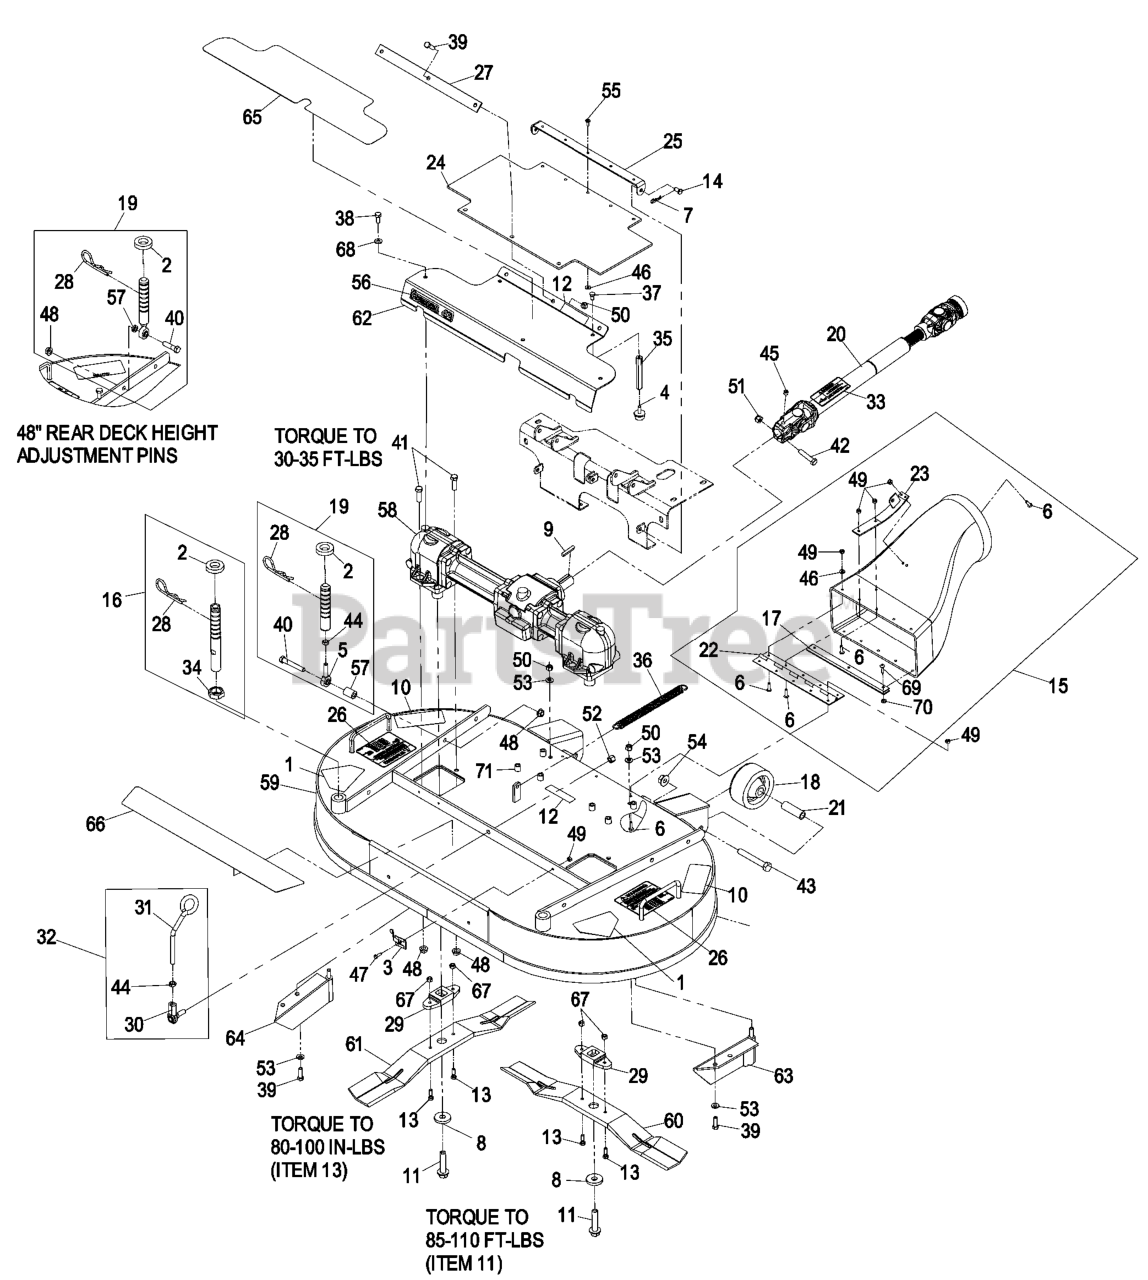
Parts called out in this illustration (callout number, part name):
1	DECAL-DANGER
2	SPACER-DECK SUPPORT
3	CLIP-DECK, HOLD UP ROD
4	BUMPER-RUBBER
5	BALLJOINT
6	SCREW-HEAD, TRUSS
7	PIN-COTTER
9	KEY-SQUARE
10	DECAL-TORQUE
11	BOLT-BLADE
12	DECAL-COVER, MISSING
13	BOLT-SHEAR
14	PIN-CLEVIS
15	DISCHARGE TUBE ASM
16	FRONT DECK HEIGHT ADJUST
17	GUARD-PLENUM
18	ROLLER-DECK
19	REAR DECK HEIGHT ADJUST A
20	DRIVE SHAFT ASM
21	SPACER-ROLLER
22	HINGE-PIANO
23	MOUNT-SPRING
24	GUARD-PTO
25	BRACKET-GUARD, PTO
27	STRAP-DRIVE, LINE COVER
28	PIN-CUT HEIGHT
29	DRIVER-BLADE
30	BALLJOINT-RH
31	LATCH-DECK
32	DECK LATCH ASM
33	DECAL-DRIVELINE
34	NUT-JAM
35	STAND-OFF
36	SPRING-EXTENSION
37	SCREW-HH
38	SCREW-HH
39	SCREW-HH
40	SCREW-HH
41	SCREW-HH
42	SCREW-HH
43	SCREW-HH
44	NUT-HEX
45	SCREW-SET, HSH
46	WASHER-FLAT
48	NUT-HHF, WHIZ
49	NUT-LOCK, NI
50	NUT-LOCK, NI
51	NUT-LOCK, NI
52	NUT-LOCK
53	WASHER-SPRING
54	NUT-HHF
55	RIVET-BLIND
56	DECAL,COMMERCIAL 42
57	TUBE-INTERLOCK
58	GEARBOX ASM
59	DECK ASM
60	BLADE,22 INCH LH
61	BLADE,22 INCH RH
62	ASM,GEARBOX COVER 42 W/DE
63	BAFFLE-LH
64	BAFFLE-RH
65	PAD-ANTI SKID
66	PAD-SKID, ANTI
67	NUT-LOCK, NI
68	WASHER-PLAIN
69	BOLT-CARR
70	NUT-LOCK, NI
71	NUT-CLINCH
